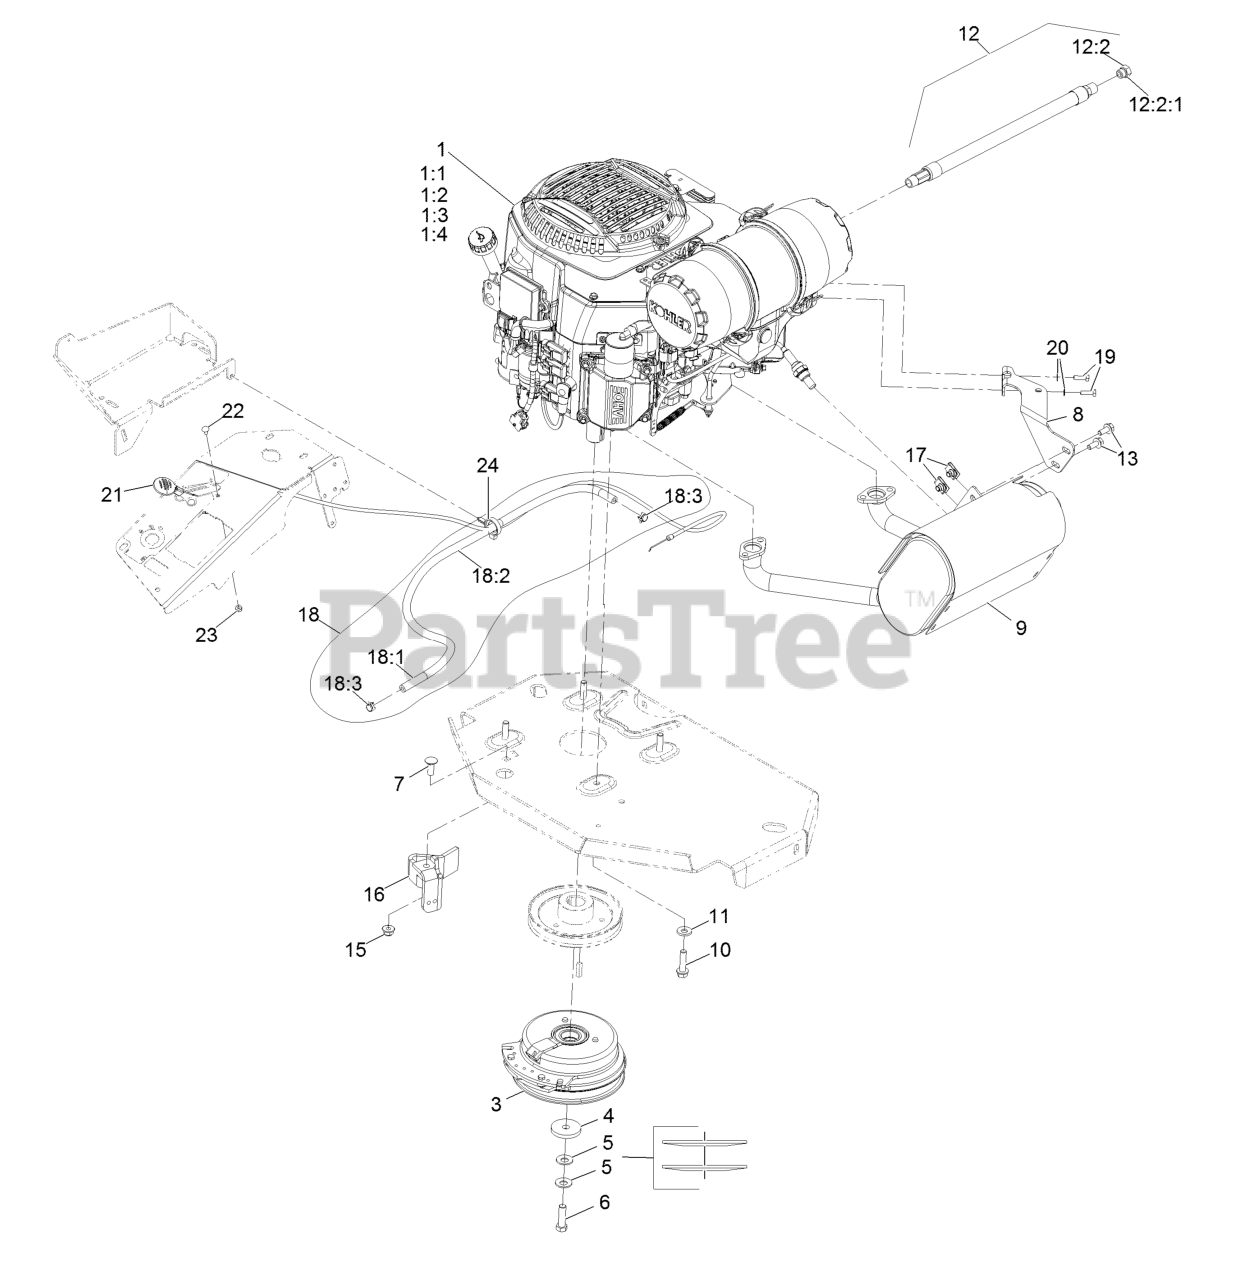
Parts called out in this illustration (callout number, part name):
1:1	Kohler 52 050 02-S Engine Oil Filter
1:2	Kohler 25 083 01-S Engine Air Filter
1:3	Kohler 25 083 04-S Safety Filter
1:4	Kohler 25 050 42-S Fuel Filter
3	Clutch Kit
4	Washer-Clutch
5	Washer-Spring
6	Screw-HH
7	Screw-CARR
8	Muffler Bracket Kit
9	Muffler Kit
10	Screw-HWH
11	Washer-Belleville
12	Oil Drain Hose ASM
12:2	Plug-HH
12:2:1	O-Ring
13	Screw-HHF
15	Nut-HF, NI
16	Clutch-Anchor
18	Fuel Line ASM
18:1	Hose-Fuel
18:2	Sleeve-Thermal
18:3	Clamp-Hose
19	Screw-HH
20	Washer-Spring
21	ASM,Throttle Cable
22	Bolt-CARR
23	Nut-Lock, NI
24	Clamp-Hose
